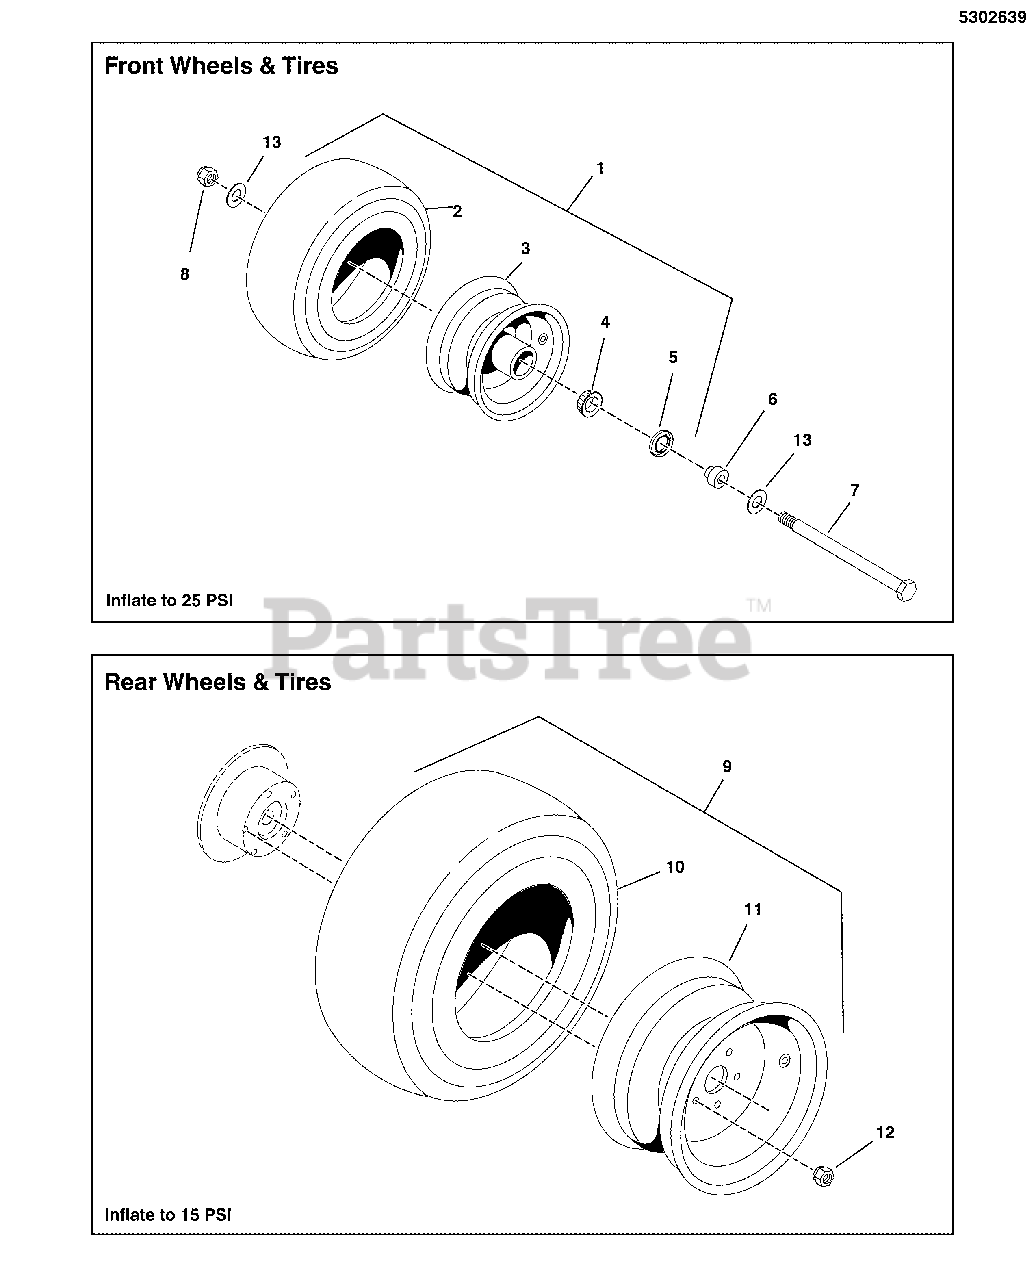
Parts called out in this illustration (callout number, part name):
1	TIRE ASSY, 13 X 6.5 SILVER
2	TIRE, FRONT, 13 x 6.5 (SV)
3	WHEEL ASSEMBLY, For 13 x 6.5 x 6 Tires, Complete (SV)
4	BEARING, Tapered Roller
5	SEAL, GREASE
6	ADAPTER, CASTER AXLE
7	BOLT, 1/2-13 X 9" GD5 YZ
8	NUT, 1/2-13 HEX NYLOCK FLANGE
9	TIRE ASSM, 24X12.00-12, SOLID
9	TIRE/WHEEL ASM, 24X12.00-12, TURF SMART
10	TIRE, REAR, 24 x 12 x 12 (SV)
10	TIRE, 24X12.00-12, TURF SMART
11	WHEEL ASSEMBLY, 12 x 8.5
12	NUT, 1/2-20, FOR WHEEL BOLT SILVER
13	WASHER, 1/2 SAE
